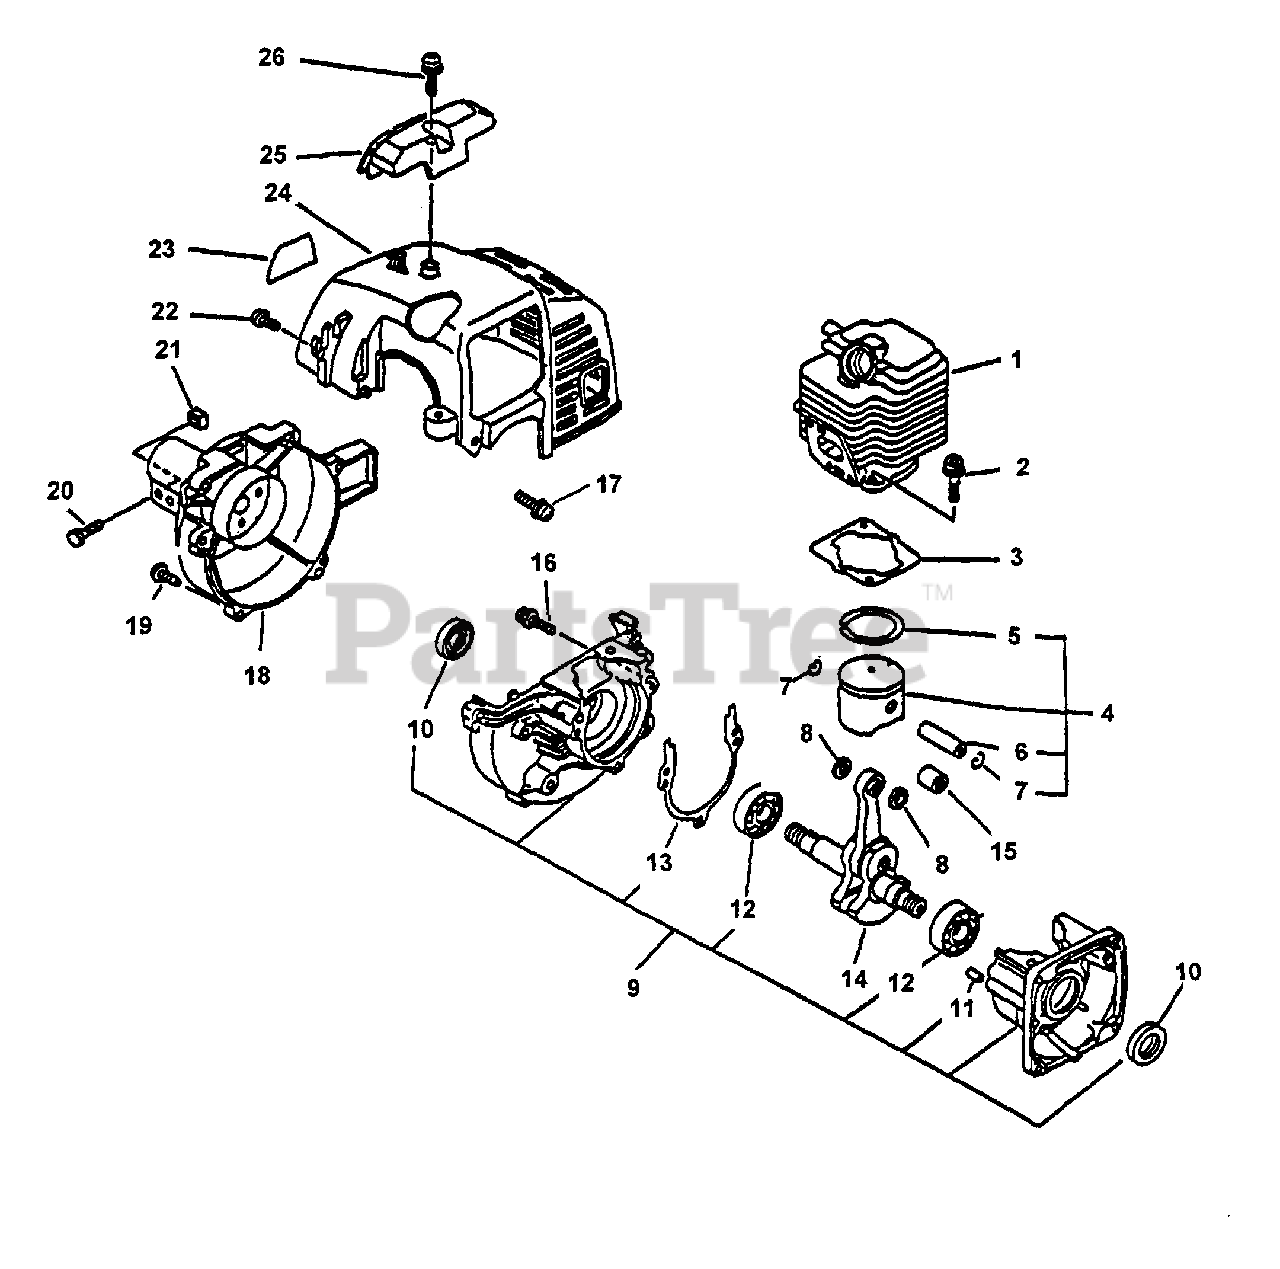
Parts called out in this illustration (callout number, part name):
1	CYLINDER
2	SCREW - 5X22
3	GASKET, CYLINDER
4	PISTON KIT
5	RING, PISTON
6	PIN, PISTON
7	RING, RETAINING
8	SPACER, PISTON
9	CRANKCASE KIT
10	SEAL, OIL
11	PIN - LOCATING
12	BEARING, BALL - 6201
13	GASKET, CRANKCASE
14	CRANKSHAFT ASSY
15	CRANKSHAFT ASSY
15	BEARING, NEEDLE
16	SCREW - 5X28
17	SCREW - 4X12 -- TAPPING
18	FAN CASE ASSY
19	SCREW - 4X18
20	BOLT - 5X28
21	NUT - 5 -- SQUARE
22	SCREW - 4X16
23	LABEL - MODEL PE-2000
24	COVER, ENGINE - GRAY
25	GUARD, TOP - GRAY
26	SCREW - 5X16 -- TAPPING
